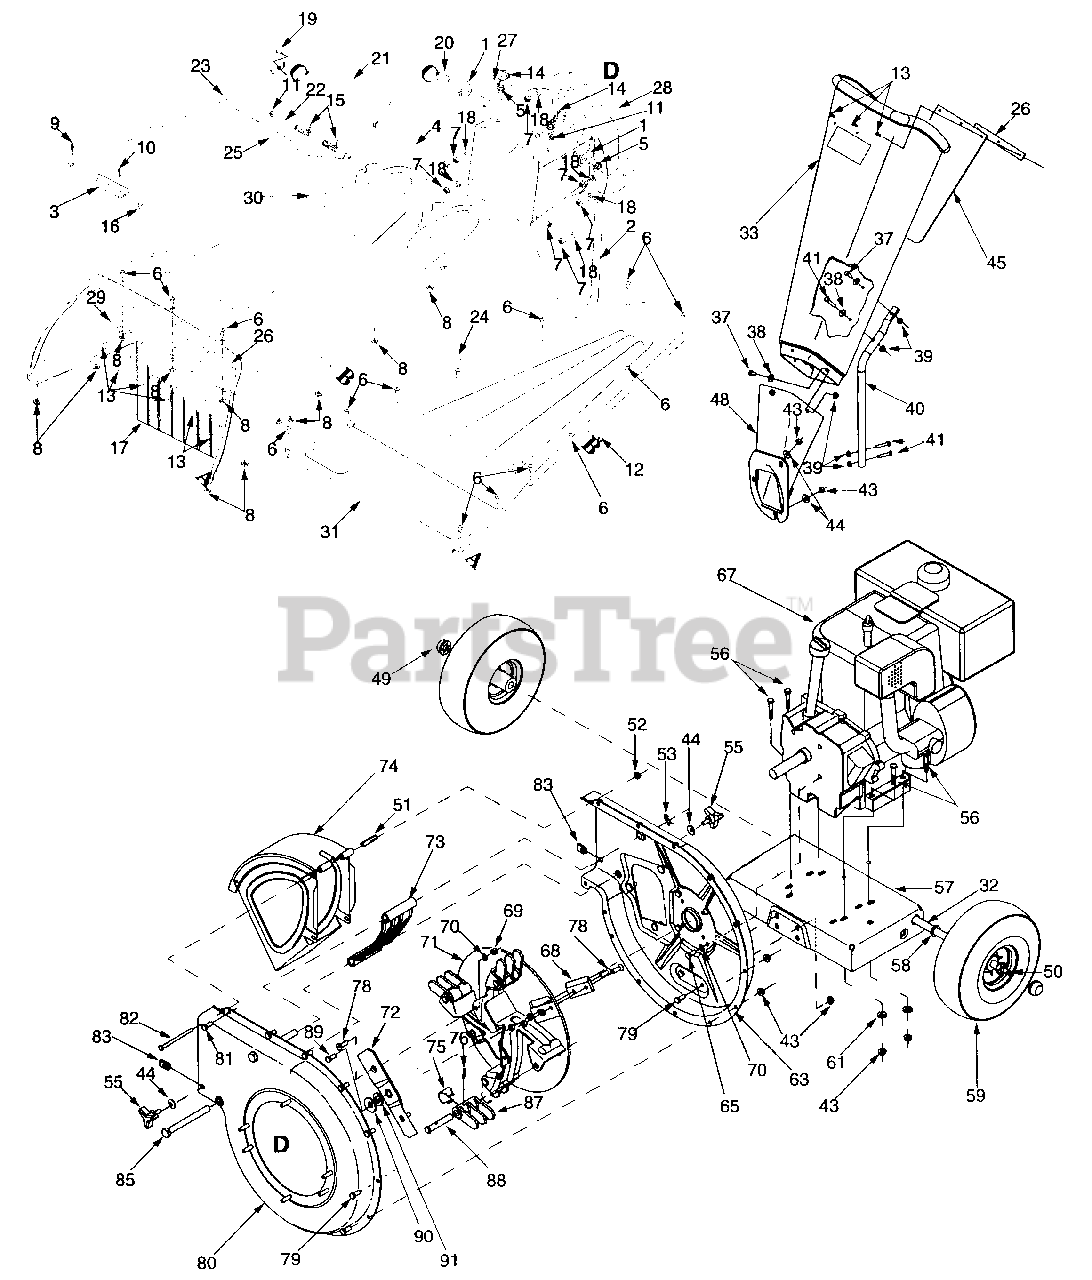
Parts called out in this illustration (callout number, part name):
1	Stop Washer
4	Hex Flange Bolt: 5/16-18 x 8.375" (Gr.5)
5	Hex Washer Head Self-Tapping Screw: 5/16-18 x 0.5"
6	Button-Head Screw 1/4-20 x 0.5"
7	Lock Nut: 5/16-18
8	Hex Flange Lock Nut: 1/4-20
9	Internal Cotter Pin
10	Spiral Pin
11	Cap Nut
12	Speed Cap Nut
13	Pop Rivet
14	Torsion Spring
15	Hopper Door Spring
16	Rubber Washer
17	Hopper Flap
18	Lock Washer
19	Shdr. Scr: .340 x .285 x 1/4-20
20	Shdr. Scr: .56 x .165 x 5/16-18
21	Rel. Rod: 5/16" dia.
22	Hopper Door Rod
23	Flap Retaining Rod
24	Flap Retaining Bail
31	Lower Hopper
32	Shredder Axle
33	Chipper Chute
37	Hex Bolt 1/4-20 x .625
38	Flat Washer .28 I.d. x .74 O.d.
39	Flanged Lock Nut
41	Hex Scr. 1/4-20 x .625 (Gr. 2)
43	Hex Nut 5/16-18 Thd. (Gr. 5)
44	Bell Washer .345" I.d. x .88"
45	Shredder Chute flap
48	Chipper Chute Assembly
49	Push Cap 5/8" dia.
50	Air Valve
51	Chute Hinge Spacer
52	Hex Ctr. Lock Nut 1/4-20 Thd.
53	Internal Cotter Pin
55	Hand Knob
56	Hex Bolt 5/16-18 x 1.5"
58	Flat Washer 1.12 x .64 x .120
59	Wheel Assembly
61	Special Lock Washer
63	Flail Housing Ass'y. - Inner
65	Hex Bolt 5/16-24 x .75" Lg.
68	Chipper Blade
69	Hex Top Lock Nut 5/16-24 (Gr. 5)
70	Lock Washer 5/16" I.d.
71	Impeller assembly
72	Shredder Blade
73	Shredder Screen
75	Retaining Clip
76	Spring Roll Pin
78	Flat Head Scr. 5/16-24 x .75"
79	Hex Bolt 5/16-18 x .75" (Gr. 5)
80	Flail Housing Ass'y. - Outer
82	Hex Bolt 1/4-20 x 3.75"
83	U Nut 5/16-18
85	Clevis Pin
87	Flail Blade
88	Clevis Pin
89	Hex Patch Bolt 3/8-24 x 2.25" (Gr. 8)
90	Lock Washer 3/8"
91	Flat Washer .406" I.d. x 1.25"
